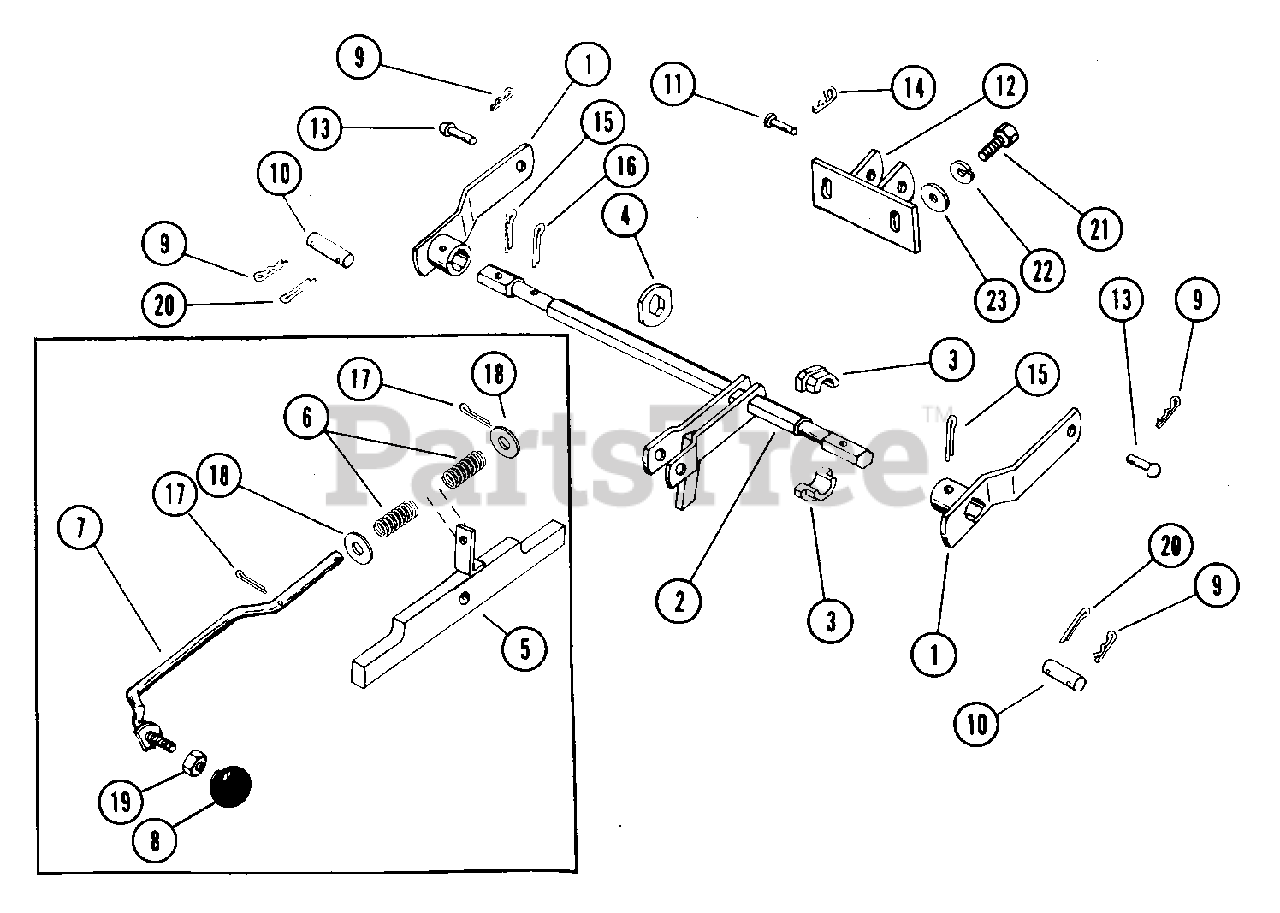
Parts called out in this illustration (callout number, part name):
2	REAR ROCK SHAFT
3	BSHG-FLG 1.000X1.750X1.000
6	SG-COMP .65X.56X1.50
7	LATCH ROD
8	KNOB-STEERING LOCK
9	PIN-HAIR INT .14X.4X2.75
11	PIN-CLEV .619X2.0 YWZC
13	PIN-CLEV .50X1.25 RH ST PL
14	PIN-HAIR INT .09X.188 PL
15	PIN-COTR .18X2.0 ZCC
16	PIN-COTR .18X1.50 PL
17	PIN-COTR .12X.75 PL
18	WSHR-FL-STL.406X.812X.065PL
19	NUT-JAM .375-16 PL
20	PIN-COTR .12X1.0 PL
21	BLT-HEX .38-16X.75 PL GR2
22	WSHR-LK .375X.094 MED PL
23	WSHR-FL-STL .438X1.0X.083 PL
